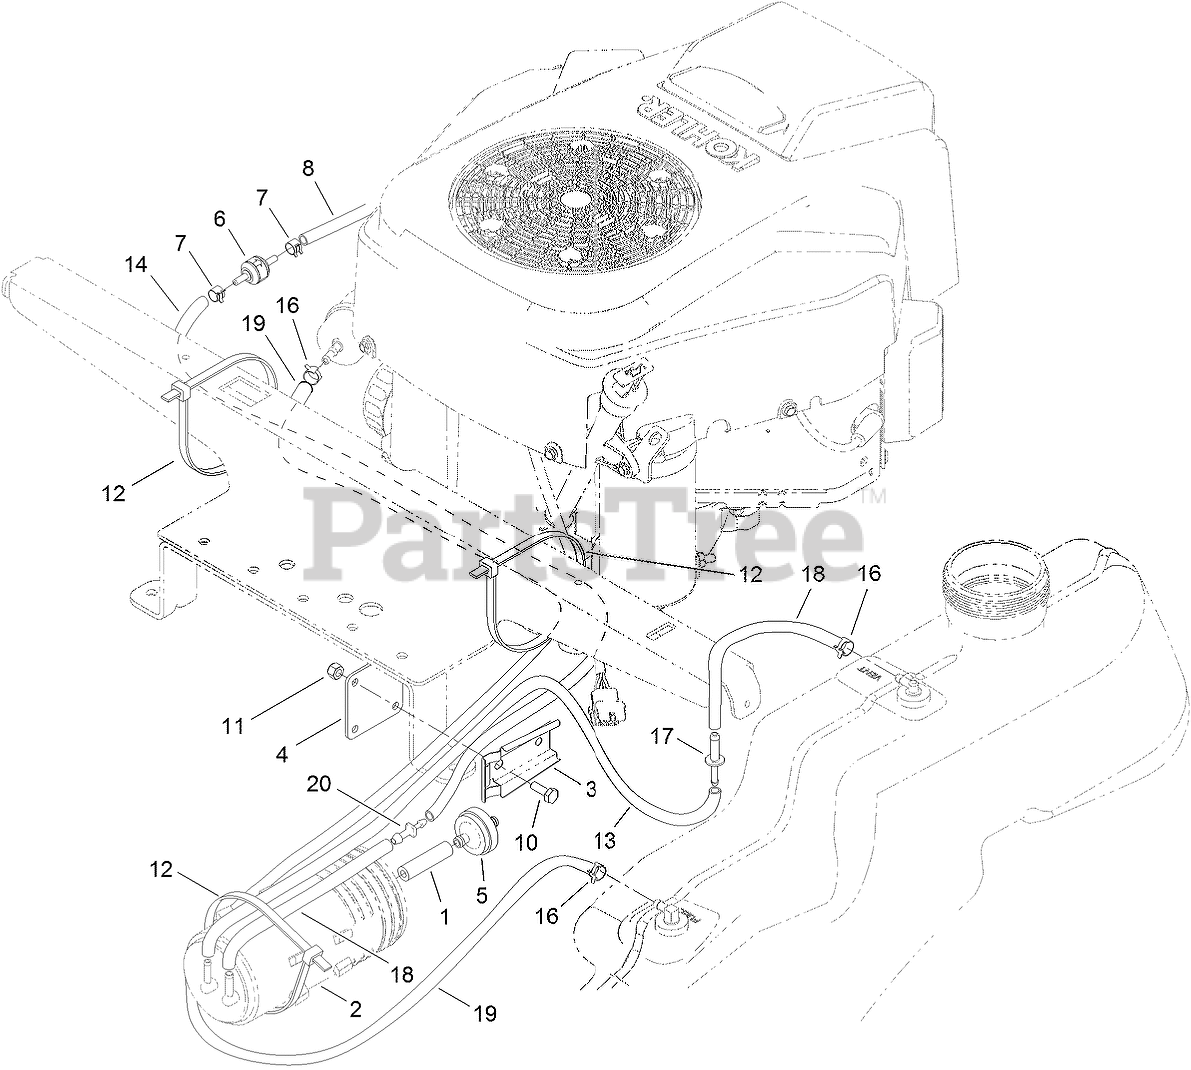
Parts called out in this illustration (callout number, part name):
1	HOSE-FUEL
2	CANISTER-CARBON, 800CC
3	BRACKET-CANISTER, CARBON
4	PLATE-ADAPTER
5	FILTER-FUEL, INLINE
6	VALVE-CHECK, VACUUM
7	CLAMP-HOSE
8	HOSE-FUEL
10	SCREW-HH
11	NUT-LOCK, NI
12	TIE-CABLE
13	HOSE-FUEL
14	HOSE-FUEL
16	CLAMP-HOSE
17	ADAPTOR-ORIFICE
18	HOSE-FUEL
19	HOSE-FUEL
20	FITTING-STRAIGHT
